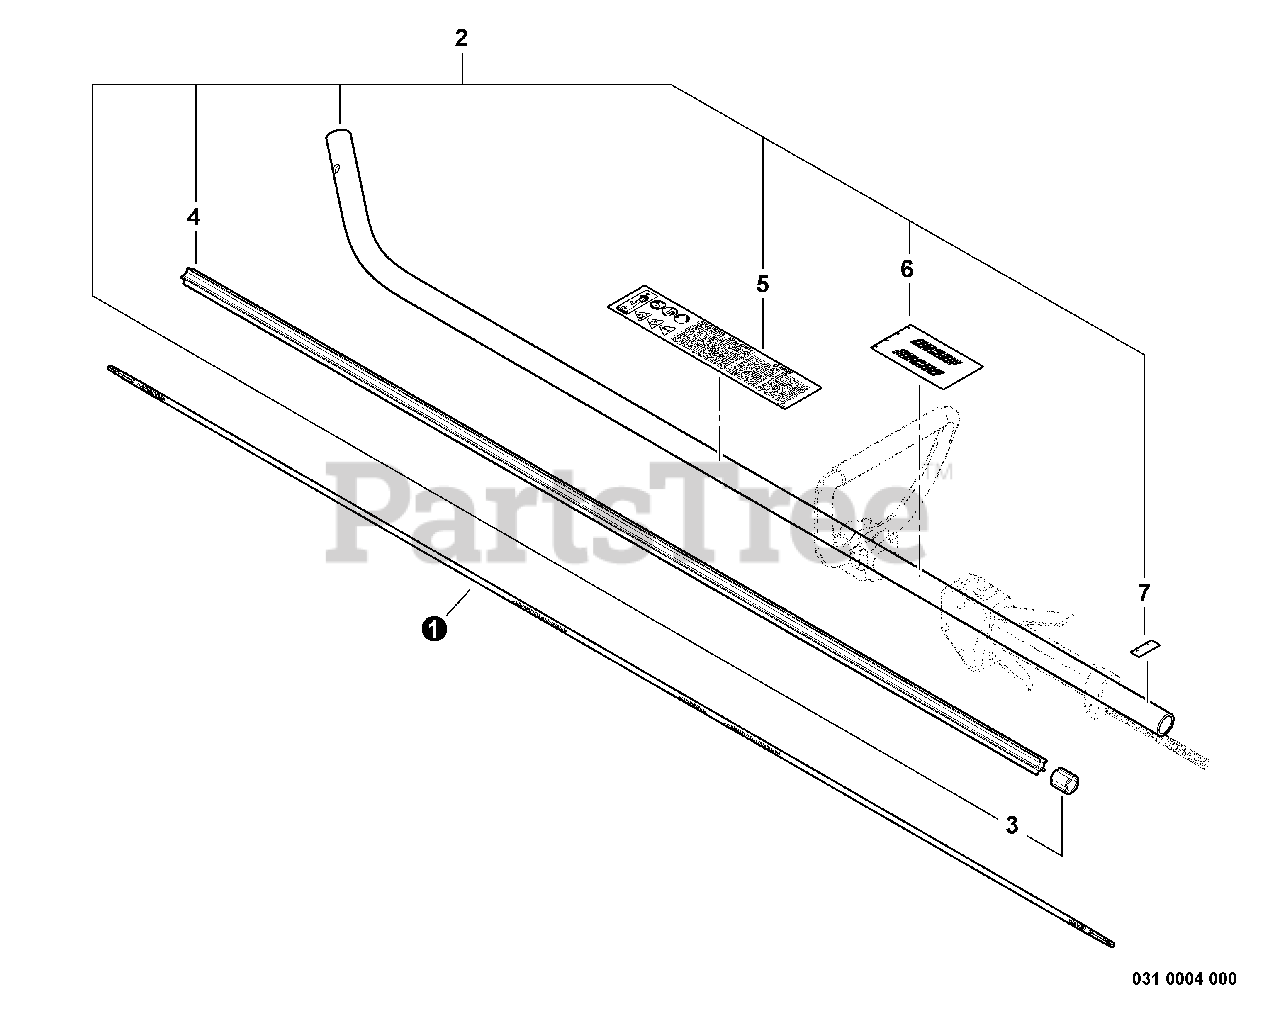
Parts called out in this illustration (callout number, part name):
1	DRIVESHAFT - FLEXIBLE
2	MAIN PIPE ASSY
4	LINER - FLEXIBLE
5	LABEL - CAUTION
6	LABEL - HANDLE LOCATION
7	LABEL - ALIGNMENT
